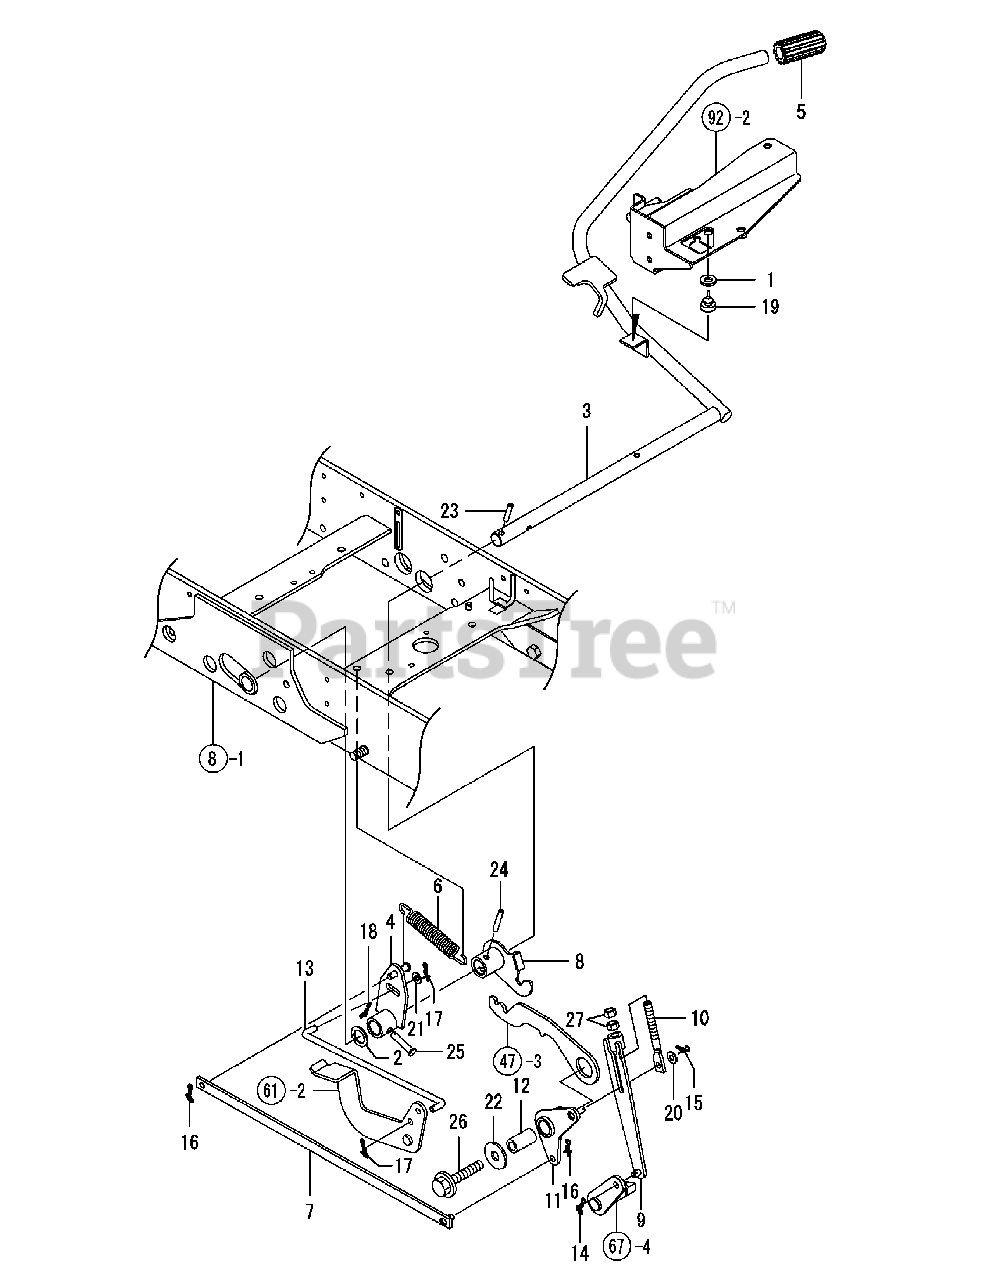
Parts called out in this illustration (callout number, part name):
2	WASHER 20X30X2
3	PEDAL CMP, BRAKE
4	ARM CMP, BRAKE
5	HEAD, BRAKE PEDAL
6	SPRING, RETURN
7	ROD CMP, BRAKE
8	ARM, RELEASE CMP
11	ARM CMP, BRAKE REAR
13	LINK ROD, DIFF
14	PIN 8, COME-OFF SNAP
15	PIN 8, COME-OFF SNAP
16	PIN 8, COME-OFF SNAP
17	PIN 8, COME-OFF SNAP
18	PIN 8, COME-OFF SNAP
19	STOPPER, PEDAL
20	WASHER 8, POLISHED
21	WASHER 8, POLISHED
23	SPRING PIN 6X32
24	SPRING PIN 6X40
